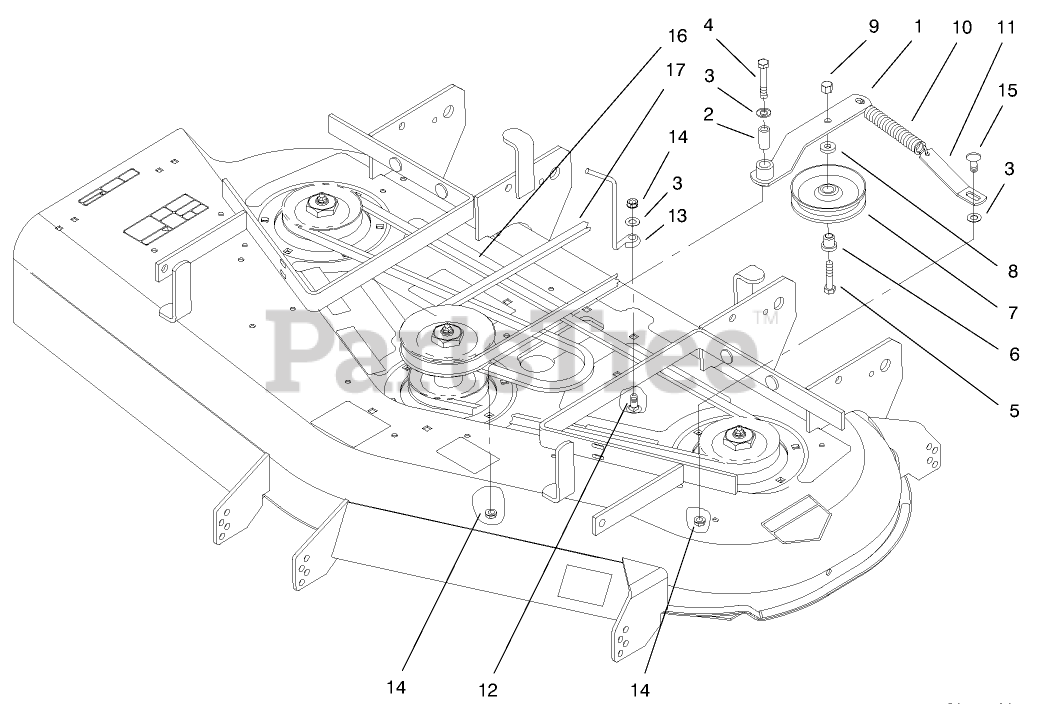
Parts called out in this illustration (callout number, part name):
1	IDLER ARM ASM
2	SLEEVE
3	WASHER-FLAT
4	SCREW-HH
5	SCREW-HH
6	BUSHING-PULLEY
7	PULLEY-IDLER
8	WASHER-FLAT
9	NUT-HEX
10	SPRING-EXTENSION
11	PLATE-SPRING
12	SCREW-CARR
13	GUIDE-BELT
14	NUT-HF
15	SCREW-CARR
16	V-BELT
17	V-BELT, DRIVE
